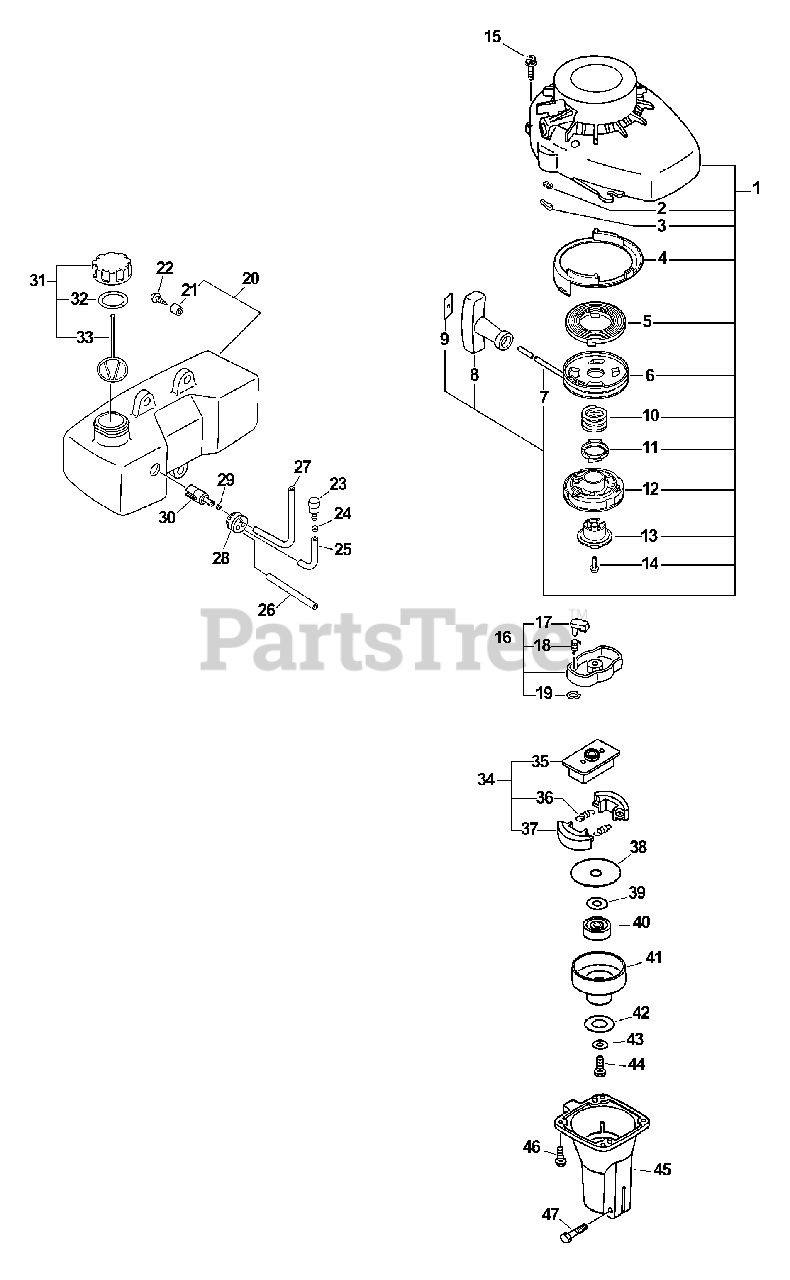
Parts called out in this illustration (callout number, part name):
1	STARTER ASSY
2	SPRING, PAWL RETURN
3	PAWL, STARTER
4	CASE, STARTER
5	SPRING, REWIND
6	REEL, ROPE
7	ROPE, STARTER - 3X800
8	GRIP, STARTER
9	RETAINER, ROPE
10	SPRING, RETURN
12	SPRING ASSY
13	PLATE, CAM
15	SCREW - 4X16
16	STARTER PAWL ASSY
17	PAWL, STARTER
18	SPRING, RETURN
19	RING, RETAINING - 4
20	FUEL TANK ASSY
22	SCREW - 5X15
23	VENT, FUEL TANK
24	CLIP - 5.5
25	PIPE - 3X5X70 -- BLACK
26	PIPE - 3X6X50 -- CLEAR
27	PIPE - 3X5X210 -- BLACK
28	GROMMET
29	CLIP - 6
30	FILTER, FUEL
31	CAP ASSY
32	GASKET, CAP
33	CONNECTOR, CAP
34	CLUTCH ASSY
35	HUB, CLUTCH
36	SPRING, CLUTCH
37	SHOE, CLUTCH
38	PLATE, CLUTCH
39	WASHER - 10
40	BEARING, BALL - 6000
41	DRUM, CLUTCH
42	WASHER, CLUTCH
43	WASHER, CLUTCH
44	SCREW - 6X12
45	CASE, CLUTCH
46	SCREW - 4X14
47	BOLT - 5X25
